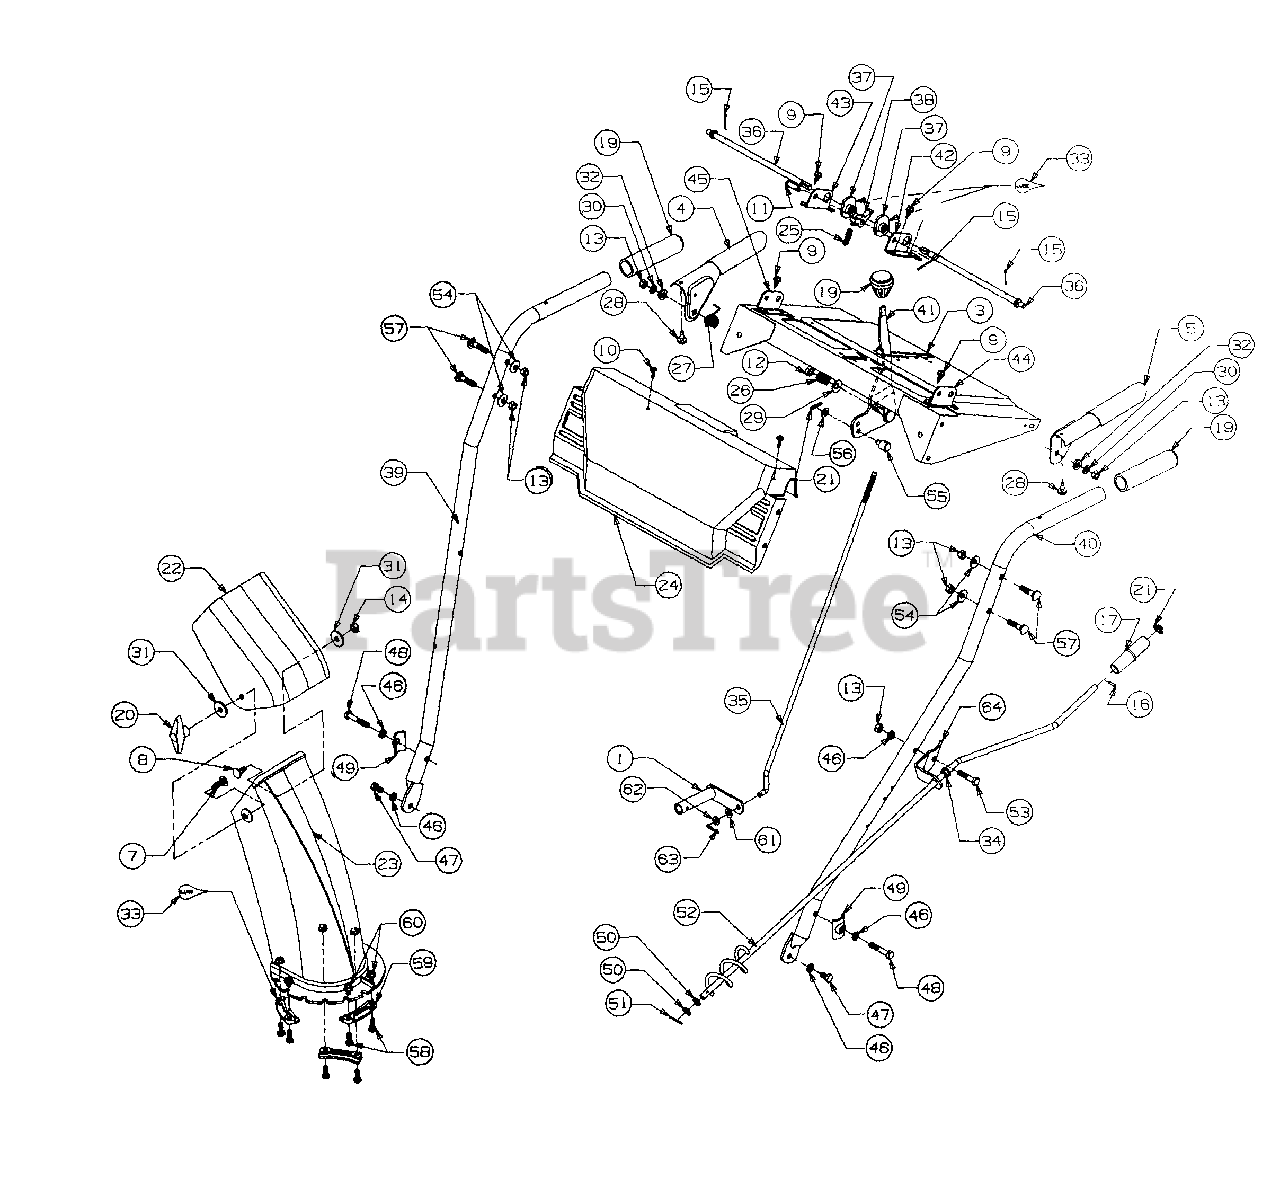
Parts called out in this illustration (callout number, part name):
5	Handle-Engagement - L.H.
7	Screw
8	Bolt-Carriage
9	Screw
10	Screw
11	Pin-Clevis
12	Nut-Hex
13	Nut-Hex
14	Nut-Lock
15	Pin-Cotter
16	Pin-Roll
21	Cap-Push
22	Chute-Upper
23	Chute-Lower
24	Panel-Handle
25	Spring
26	Spring
27	Spring
28	Bumper
29	Washer-Bell
30	Washer-Lock
31	Washer
32	Washer
33	Lubricant
34	Bushing-Plastic
35	Rod-Shift
36	Rod-Cam
37	Cam-Handle Lock
38	Pawl-Handle Lock
46	Washer-Lock
47	Screw
48	Screw
49	Tab-Handle
50	Washer-Flat
51	Pin-Cotter
52	Crank-Chute
53	Screw
54	Washer-Bell
55	Ferrule
56	Washer-Flat
57	Bolt-Carriage
58	Screw
59	Keeper-Chute Flange
60	Nut-Lock
61	Washer-Spring
62	Washer-Flat
63	Pin-Cotter
